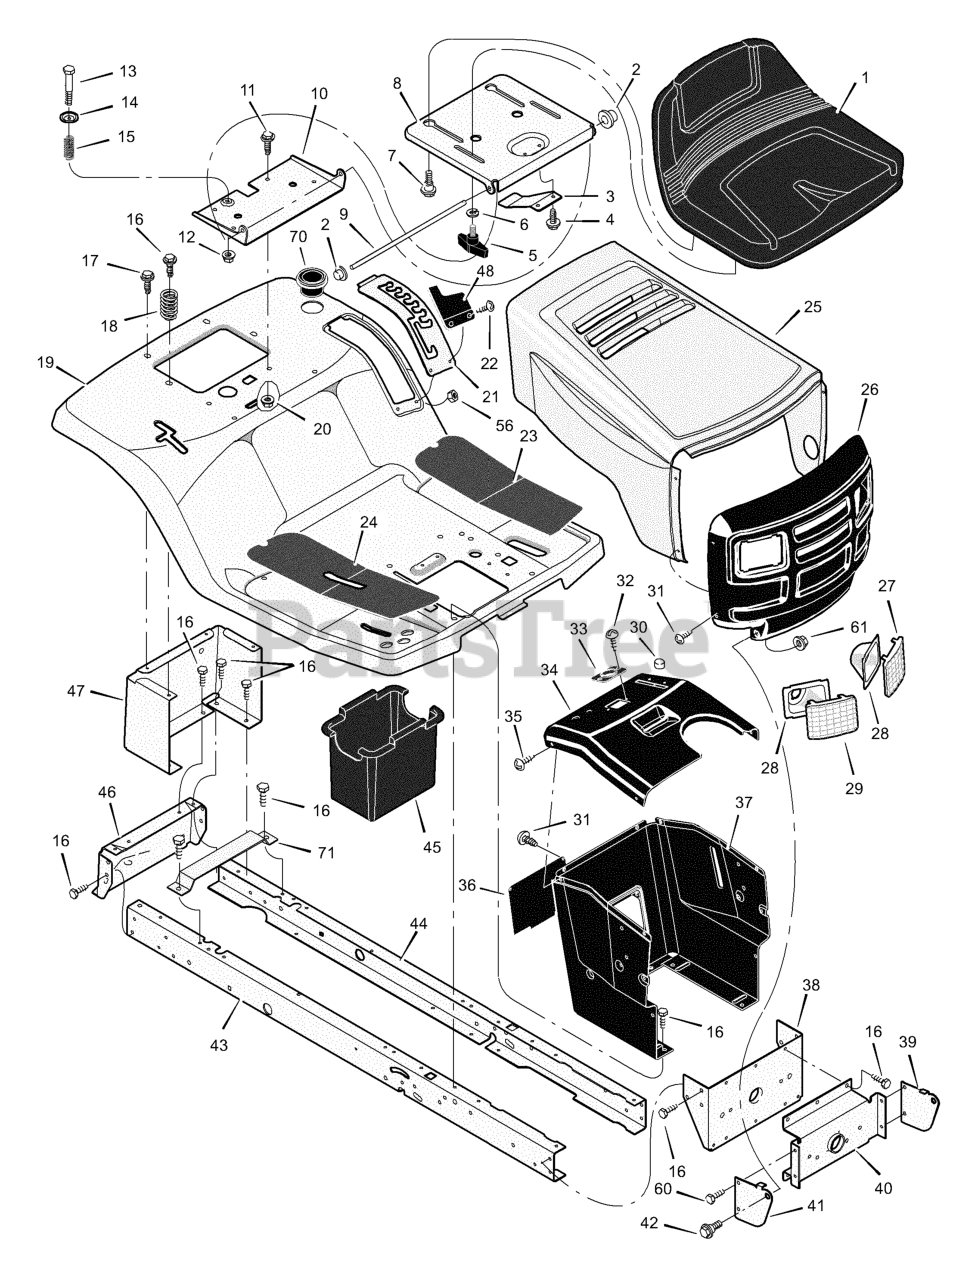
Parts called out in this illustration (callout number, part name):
1	Seat
2	Cap, Push On
5	Bolt, Wing
6	Washer
7	Bolt, Shoulder
8	Support, Seat
9	Rod, Pivot
10	Bracket, Pivot
11	Bolt
13	Bolt, Shoulder
15	Spring
19	Deck, Seat
20	Nut
21	Plate, Index
23	Mat, Left
24	Mat, Right
27	Lens, Left
28	Reflector, Headlight
29	Lens, Right
30	Plug, Dome
31	Screw
33	Bearing, Steering
36	Panel, Access
37	Support, Dash
38	Bracket, Rear Hanger
39	Support, Left Grille
40	Axle, Hanger
41	Support, Right Grille
42	Bolt, Shoulder
43	Frame, Right
44	Frame, Left
45	Container, Battery
46	Plate, Hitch
47	Panel, Rear
48	Cover, Detent
56	Locknut
61	Locknut
70	Holder, Cup
71	Support, Battery
